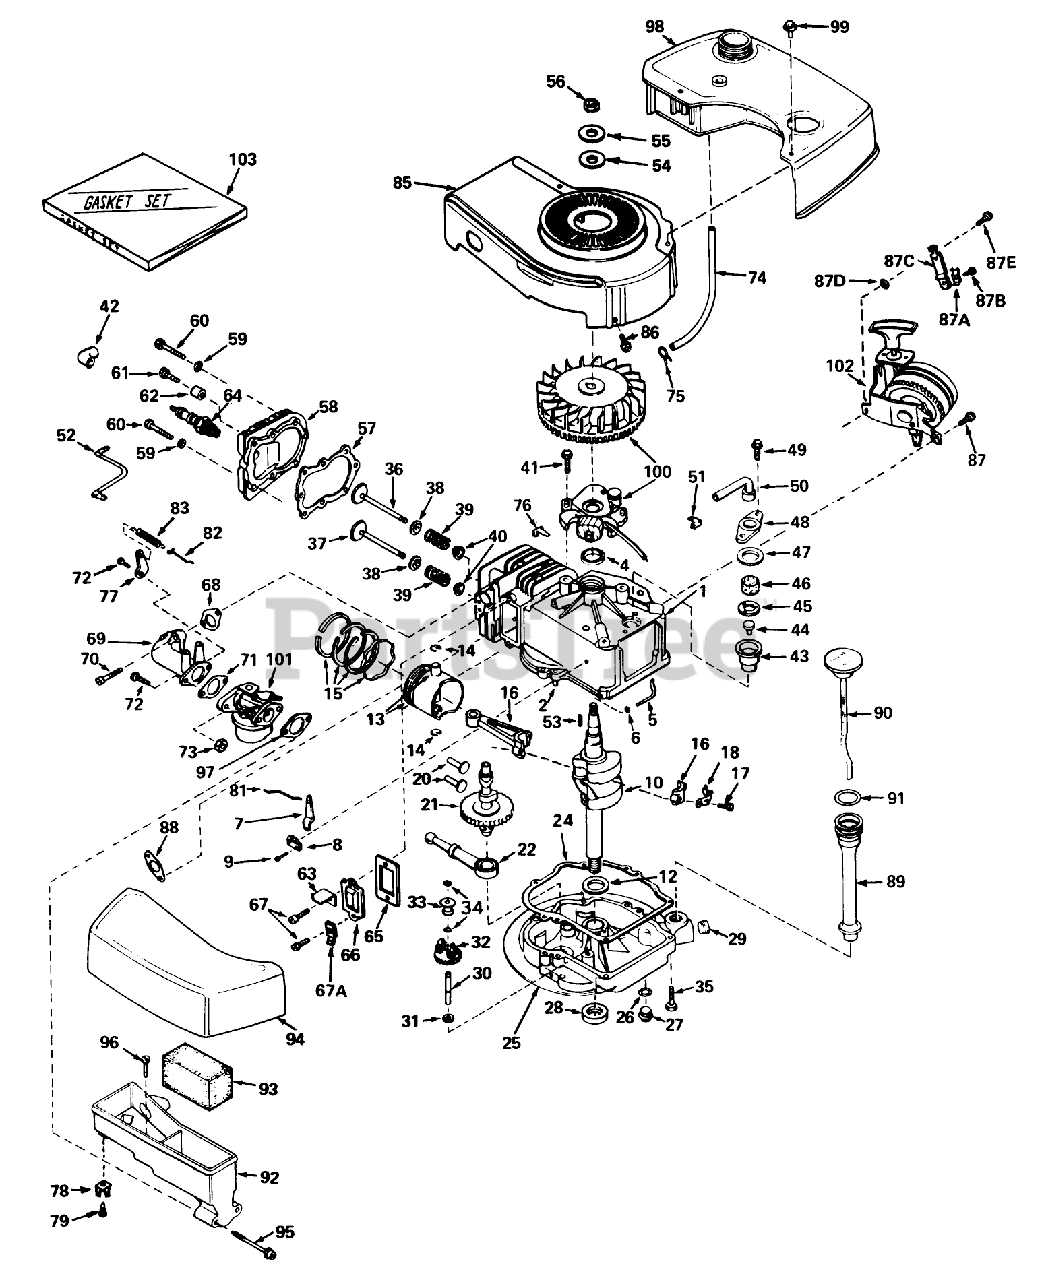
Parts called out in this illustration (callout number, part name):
1	Cylinder Assembly (Incl. Nos. 2, 4 87)
2	Pin-Dowel
4	Seal-Oil
5	Rod, Governor (Incl. No. 36)
6	Washer-Flat
7	Governor Lever
8	Clamp-Lever, Governor
9	Screw
10	Crankshaft
12	Washer-Thrust
13	Piston Pin Assembly (Incl. 2 of No. 14)(Std.)
13	Piston Pin Assembly (Incl. 2 of No. 14)(.010 Oversize)
13	Piston Pin Assembly (Incl. 2 of No. 14)(.020 Oversize)
14	Ring-Retaining, Piston Pin
15	Ring Set-Piston Std.
15	Ring Set-Piston .010 oversize
15	Ring Set-Piston .020 oversize
16	Rod Assembly, Connecting (Incl. Nos. 17 18)
17	Connecting Rod Bolt
18	Plate Lock
20	Lifter-Valve
21	Camshaft(Mech.Comp. Release)
22	Oil Pump ASM
24	Gasket, Mounting
25	Flange Assembly, Mounting (Incl. #27, 28, 29 30)
26	Gasket-Oil Drain
27	Plug Oil Drain
28	Seal-Oil
29	Plug Oil Drain
30	Shaft-Governor
31	Washer-Flat
32	Gear Assembly, Governor
33	Spool, Governor
34	Ring-Retaining
35	Screw (1/4-20 x 1-1/4)
36	Valve, Intake (Incl. Ref. #38, 39 40) (Std.)
36	Valve, Exhaust (1/32" Oversize) (Incl. Nos. 8, 9 10)
37	Valve, Exhaust (Standard) (Incl. Nos. 8, 9 10)
37	Valve, Exhaust (1/32" Oversize) (Incl. Nos. 8, 9 10)
38	Cap-Upper Valve Spring
39	Spring-Valve
40	Cap-Valve, Spring
41	Screw
42	Cover-Spark Plug
43	Body Breather Tube
44	Valve Check
45	2000A37 WIZARD ROTA
46	Element-Breather
47	Gasket-Breather
48	Cover Breather
49	Screw, Hex Hd. w/Conical
50	Tube, Breaker
51	Clip, Breather
52	Wire, Ground
53	Key Flywheel
54	Washer Flat
55	Washer, Belleville
56	Nut, Flywheel
57	Oil Fill Tube
58	Head Cylinder
59	Washer
60	Screw
61	Screw Hex Hd. Cap
62	Space
63	Retainer Clip
64	Plug, Spark (J17LM or equiv.)
65	Gasket-Breather
66	Cover-Valve
67	Screw
67A	Terminal
68	Gasket, Intake
69	Pipe, Intake
70	Screw (1/4-20 x 1)
71	Gasket-Carburetor
73	Nut and Lock Washer (1/4-28)
74	Line-Fuel
75	Clamp-Line, Fuel
76	Clip-Wire
77	Lever-Adjusting, R P M
78	Terminal
79	Screw
81	Link Governor
82	Link Governor Spring
83	Spring Governor
85	Housing, Blower
86	Screw
87	Screw (1/4-20 x 1/2)
87A	Conduit
87B	Screw (10-32 x 3/8)
87C	Bracker
87D	Washer
87E	Screw (1/4-20 X 5/8)
88	Gasket Exhaust
89	Tube, Oil Filler
90	Dipstick, OiI (Incl. No. 91)
91	O-Ring
92	Body Air Cleaner
93	Filer, Air
94	Cove, Air Cleaner
95	Screw Fil Hd.
96	Screw, Hex Hd.
97	Gasket-Air Cleaner
98	Tank Fuel
99	Screw (10-32 x 35/64)
100	LEVER
101	Carburetor
102	Starter
103	53024/VAR.16HP O/P
